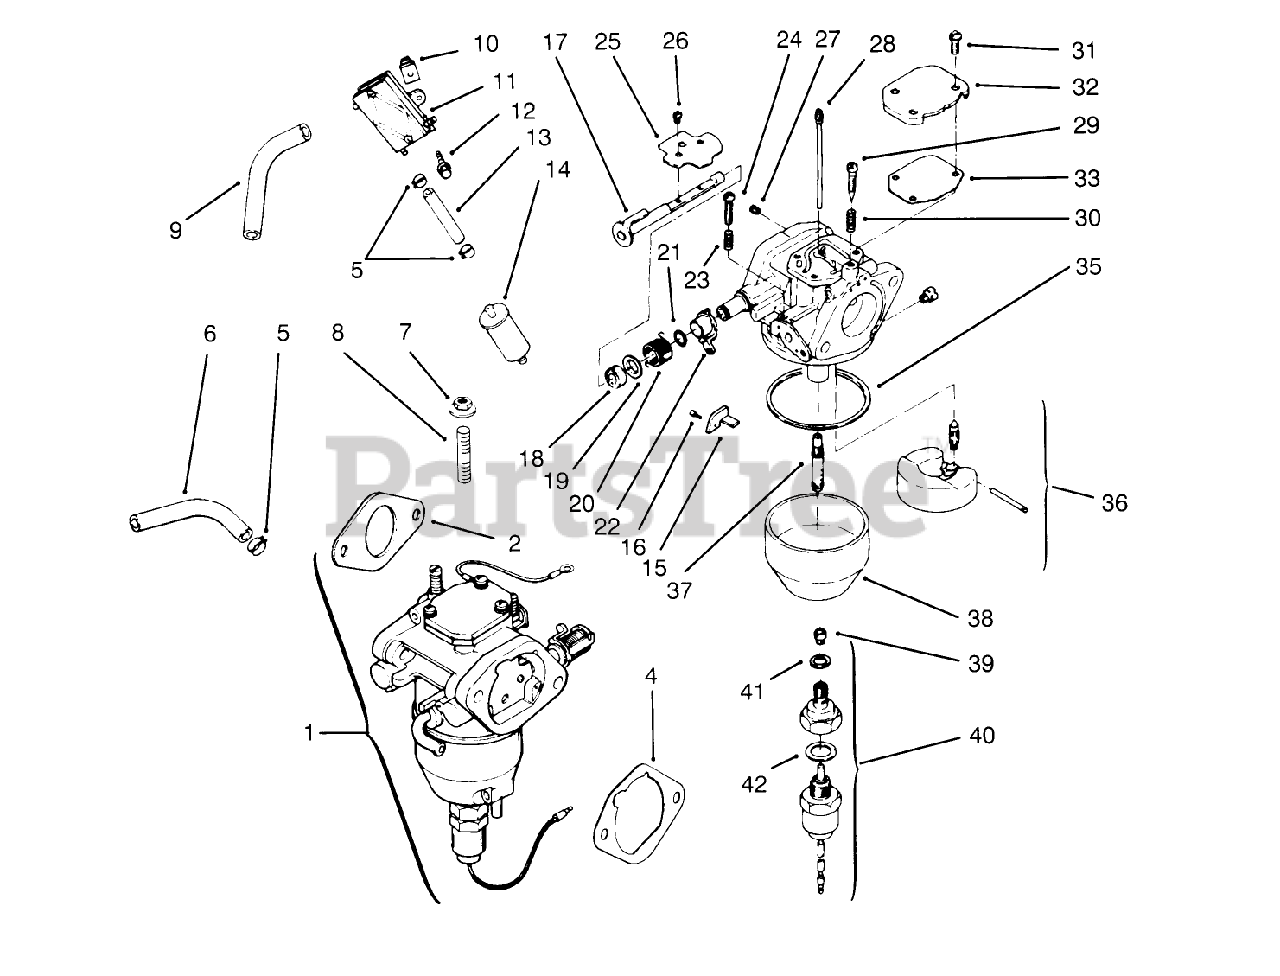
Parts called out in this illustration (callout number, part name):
1	Kit-Carb INCL 2/4/15-42 (Only On: 72103)
2	Gasket-Carburetor (Only On: 72103)
4	Gasket-A/C Base (Only On: 72103, 72083)
5	Clamp
6	Line-Fuel 10 1/2" (Only On: 72103, 72083)
8	Stud M6x1.0x95 (Only On: 72103, 72083)
9	Line-Fuel 12" (Only On: 72103)
11	Pump-Fuel
13	Line-Fuel 3 1/2" (Only On: 72103)
14	Filter-Fuel (Only On: 72042,72043,72062,72063)
15	Bracket-Throttle Stop (Only On: 72103, 72083)
16	Screw M2.5X45X5.5 (Only On: 72103)
17	Shaft-Choke (Only On: 72103, 72083)
18	Washer (Only On: 72103, 72083)
19	Collar-Choke (Only On: 72103, 72083)
20	Spring-Choke Return (Only On: 72103, 72083)
21	Ring-Choke Lever (Only On: 72103)
22	Lever-Choke (Only On: 72103)
23	Spring-Throttle Screw (Only On: 72103, 72083)
24	Screw-Throttle Adjust (Only On: 72103, 72083)
25	Valve-Choke (Only On: 72103)
26	Screw-Throttle Shaft (Only On: 72103, 72083)
27	Jet-Air Bleed (Only On: 72103)
28	Jet-Slow (Only On: 72103)
29	Screw-Idle Adjust (Only On: 72103, 72083)
30	Spring-Idle Adjust Screw (Only On: 72103)
31	Screw (Only On: 72103)
32	Cover-Passage (Only On: 72103, 72083)
33	Gasket-Passage Cover (Only On: 72103, 72083)
35	Gasket-Float Chamber (Only On: 72103)
36	Kit-Float Repair (Only On: 72103)
37	Nozzle-Main (Only On: 72103,72083)
38	Chamber-Float (Only On: 72103)
39	Jet-Main (Only On: 72103)
40	Kit-Solenoid INC 41-42 (Only On: 72103, 72083)
41	Gasket-Chamber Screw (Only On: 72103)
42	Gasket-Solenoid (Only On: 72103, 72083)
